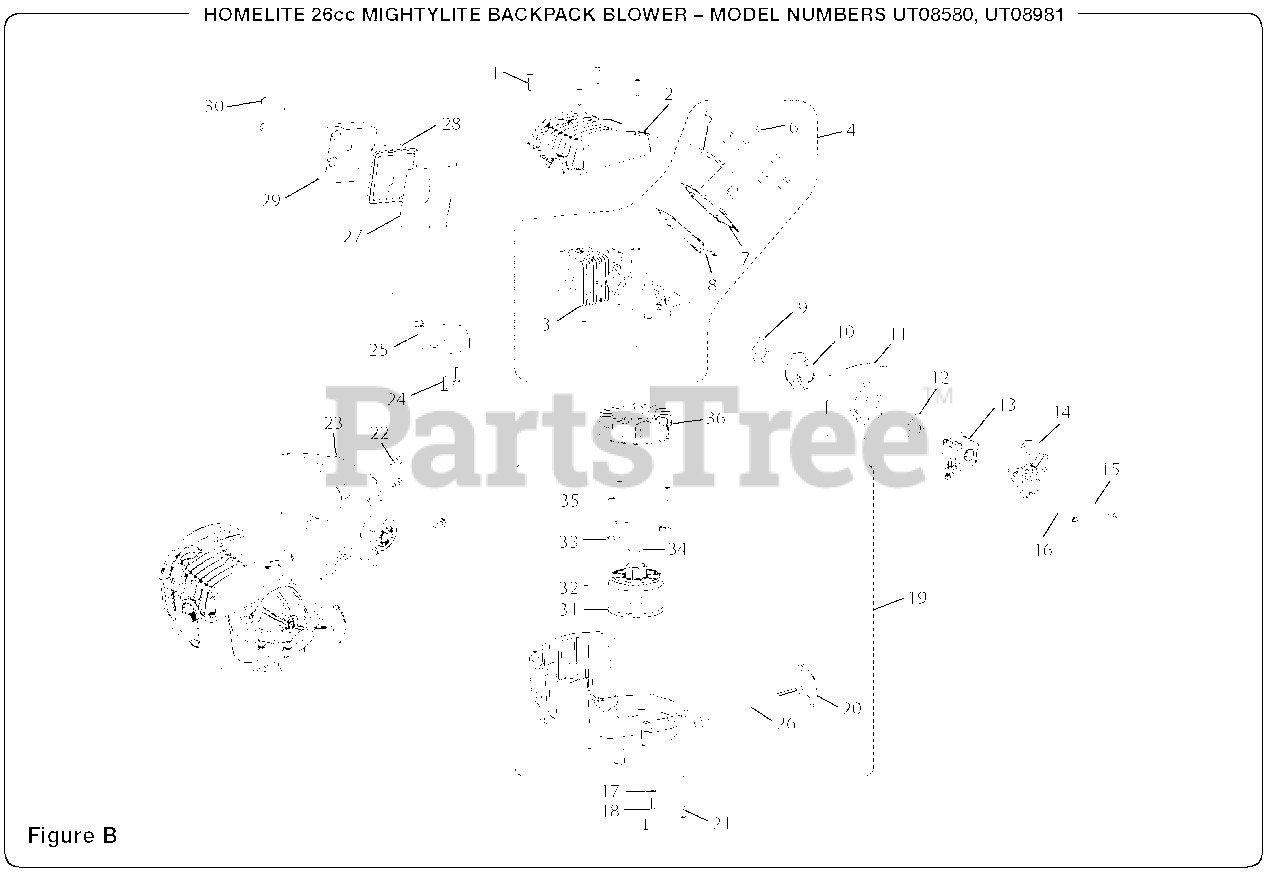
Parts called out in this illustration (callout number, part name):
1	Screw (M4 x 18 mm)
2	Upper Housing
3	Cylinder
4	Short Block Assembly (Inc. Key Nos. 3 and 5-8)
5	Cylinder Heat Shield
6	Screw (M4 x 12 mm)
7	Crankcase Cover
8	Crankcase Cover Gasket
9	Intake Gasket
11	Baffle Plate
12	Carburetor Gasket
13	Carburetor
14	Air Box Base
15	Hex Bolt (Double Sided)
16	Screw (M5 x 70 mm)
17	Flat Washer
19	Lower Housing with Starter Assembly (Inc. Key Nos. 20, 26 and 31-35)
20	Starter Grip
21	Screw (M4 x 16 mm)
22	Screw (M4, Special)
23	Fuel Tank with Cap Assembly
24	Screw (M4 x 19 mm)
25	Ignition Module
26	Starter Rope
27	Muffler Gasket
28	Muffler Assembly
29	Heat Shield
30	Screw (10-24)
31	Spring & Container Assembly
32	Starter Pulley
33	Pulley Retainer
34	Flat Washer
35	Screw (M4 x 14 mm)
36	Flywheel Assembly
